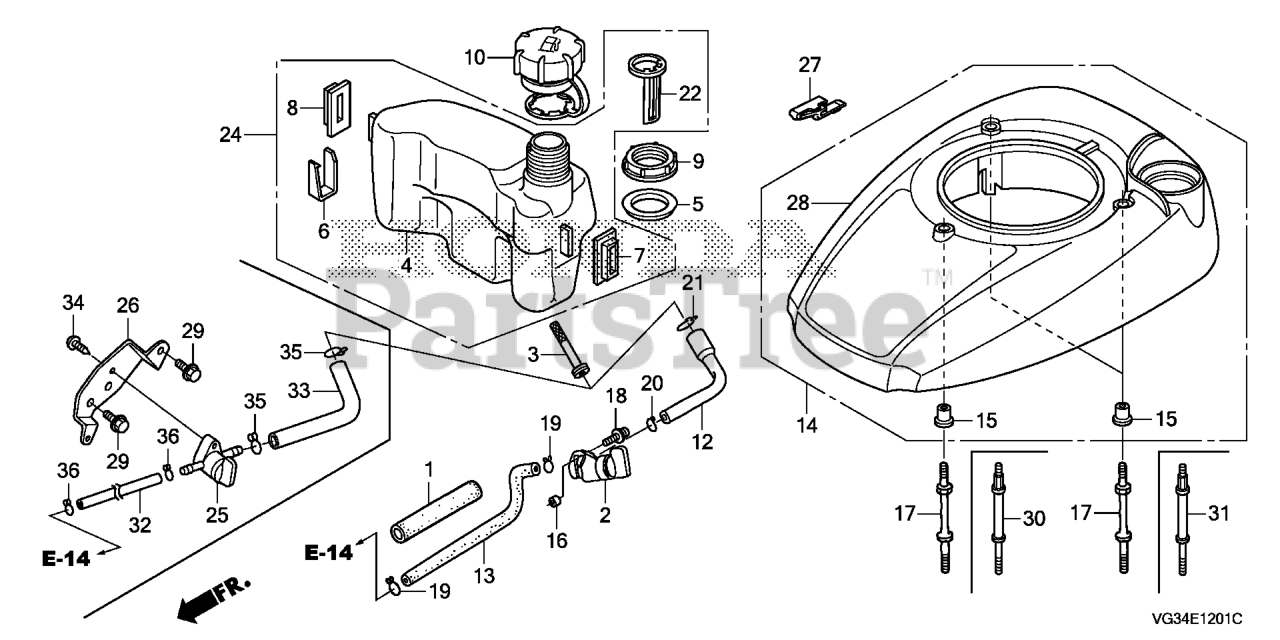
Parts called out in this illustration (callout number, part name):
3	FILTER, FUEL
4	TANK, FUEL
5	SEAL, FUEL FILLER NECK
7	RUBBER A, TANK MOUNTING
8	RUBBER B, TANK MOUNTING
9	NUT, TANK MOUNTING
10	CAP ASSY., FUEL TANK
22	GAUGE, FUEL LEVEL
25	PETCOCK ASSY.
26	STAY, PETCOCK
27	CLIP, TANK MOUNTING *R280* (POWER RED)
27	CLIP, TANK MOUNTING *NH1* (BLACK)
28	COVER, FAN *R280* (POWER RED)
29	BOLT, FLANGE (6X14)
30	BOLT, STUD (FAN COVER)
31	BOLT, STUD (FAN COVER)
32	TUBE, FUEL (4.5X110)
33	TUBE, FUEL (7.3X160)
34	SCREW, TAPPING (5X12) (PO)
35	CLIP, TUBE (B12.5)
36	CLIP, TUBE (C9)
